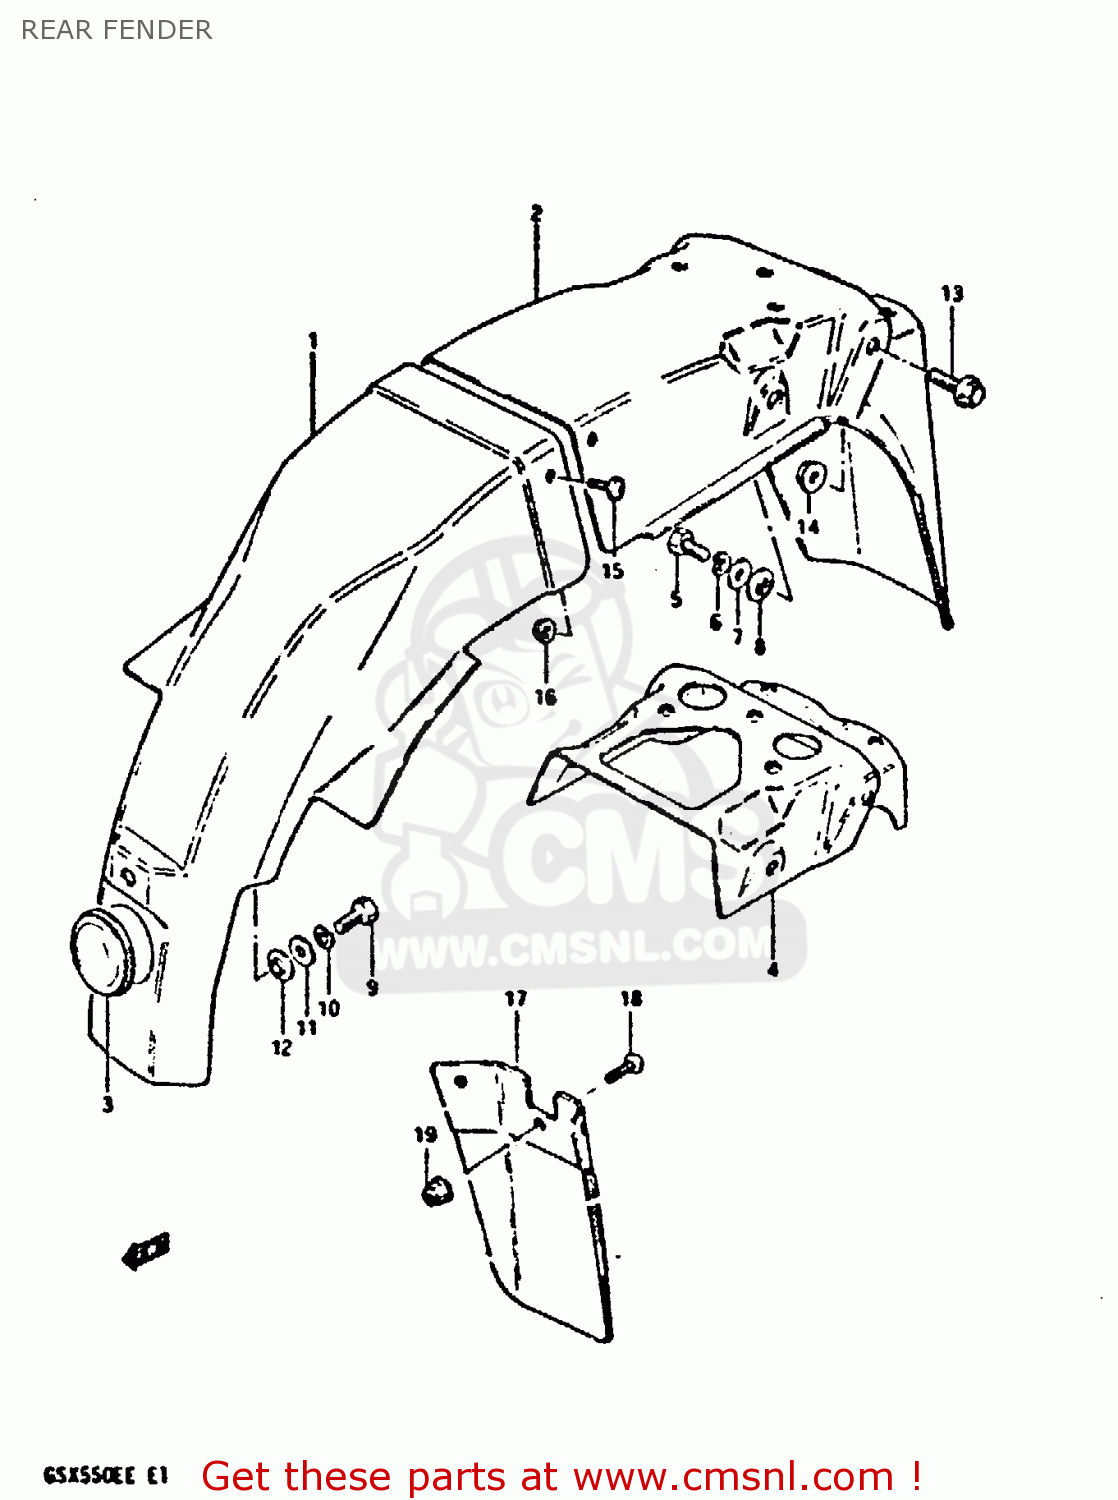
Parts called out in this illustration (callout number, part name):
1	BODY,REAR FENDER,FRONT
2	BODY,RR FENDER RR
3	GROMMET,REAR FENDER,FRONT
4	REINFORCEMENT,REAR
5	BOLT
6	LOCK WASHER
7	WASHER
8	WASHER
9	BOLT, UPPER
10	LOCK WASHER
11	WASHER 6MM
12	WASHER
13	BOLT
14	NUT
15	SCREW
16	NUT
